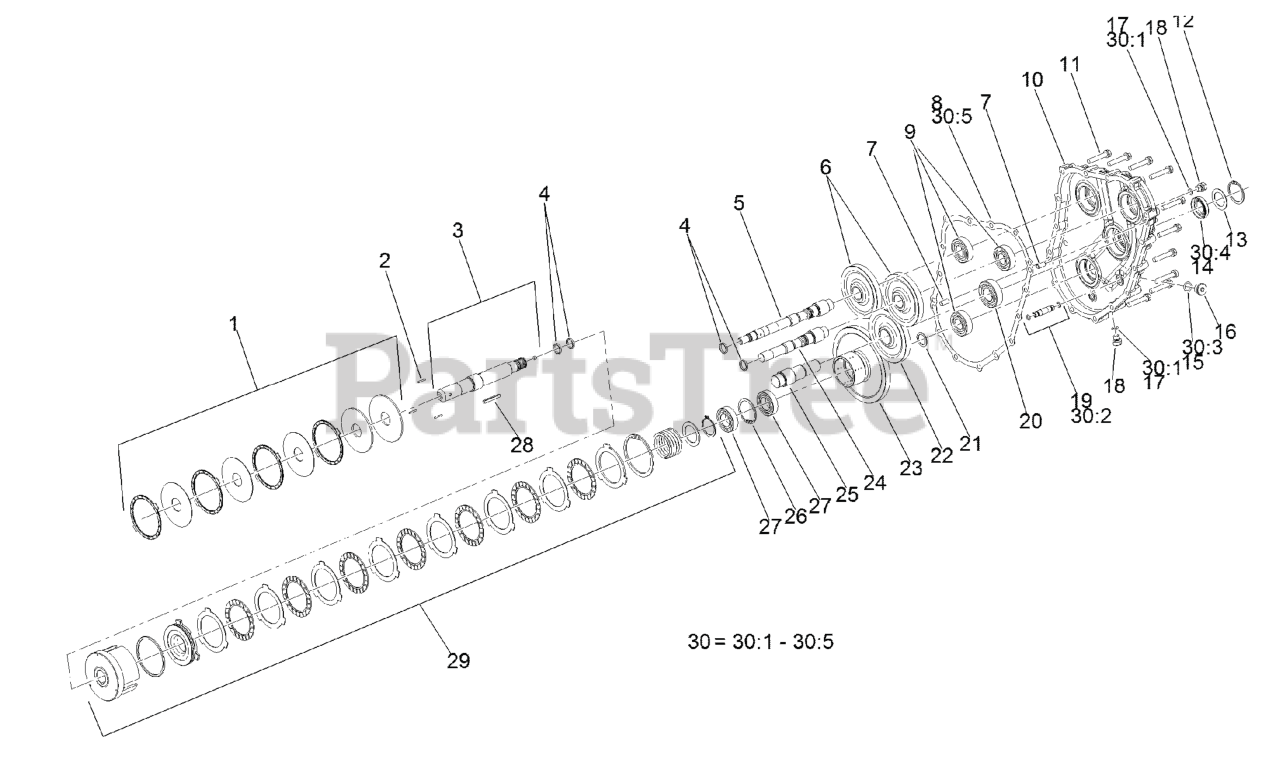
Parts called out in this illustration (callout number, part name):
1	PTO BRAKE ASM
2	ROD-PUSH
3	PTO SHAFT ASM
4	RING-SEAL
5	SHAFT-PUMP
6	GEAR-PUMP
7	PIN-PARALLEL
8	GASKET-HOUSING, GEAR
9	BEARING
10	HOUSING-CASE, GEAR
12	RING-SNAP
15	Packing
16	PLUG-NPTF
17	O RING-PLUG
20	BEARING
22	GEAR-INPUT
23	GEAR-PTO
24	SHAFT-PUMP
25	SHAFT-INPUT
26	RING-SNAP
27	BEARING
29	CLUTCH CYLINDER ASM
30	GEAR HOUSING SEAL KIT
30:1	O RING-PLUG
30:2	O-Ring
30:3	Packing
30:5	GASKET-HOUSING, GEAR
